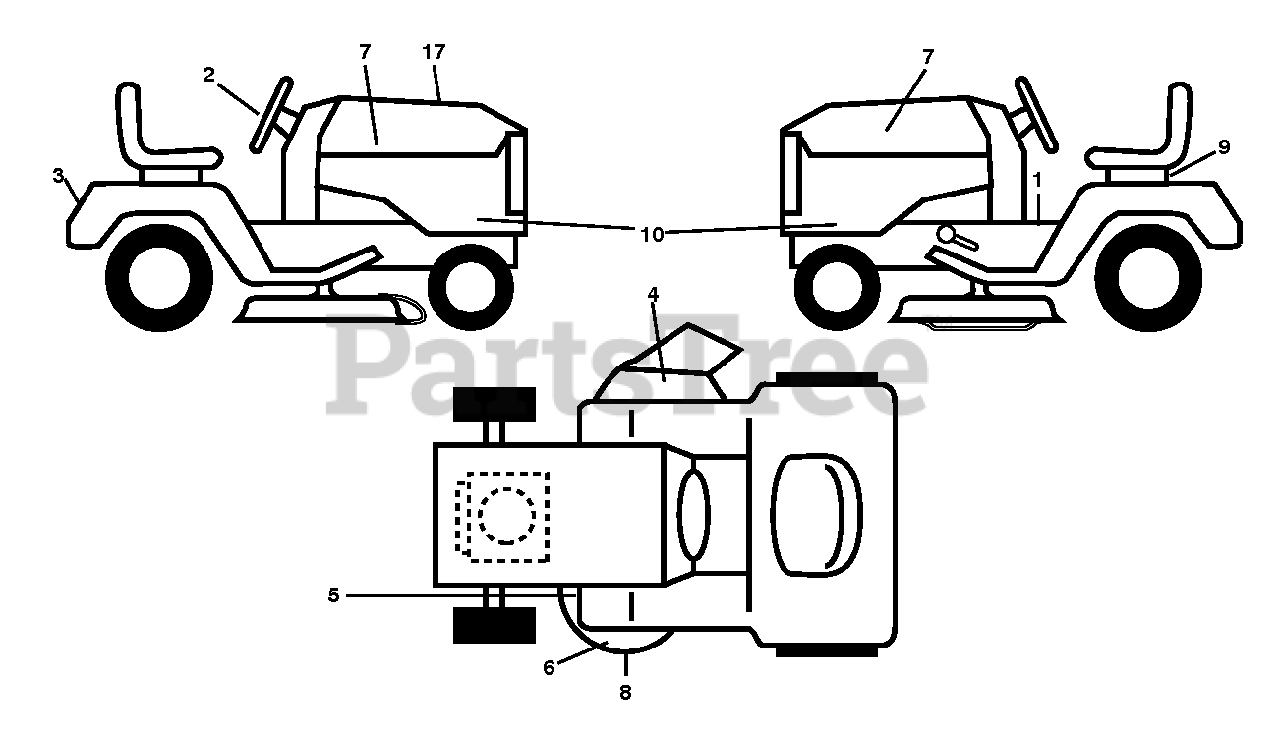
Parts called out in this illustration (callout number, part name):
1	DECAL.FENDER.WARNING.ENGLISH
2	DECAL.STRWHL.BLK.2014.PPRO
3	DECAL.REARFNDR.POULAN PRO.2015
4	DECAL, DECK DEFLECTOR, WARNING
5	DECAL.V-BELT.SCH.42/46"MEC/ELE
6	DECAL.MOWER.CAUTION.TENSION.AR
7	DECAL.POULAN PRO.2015
8	DECAL.PPRO.10YRDECKWAR.POP
9	DECAL BTRY SYMBOLS
